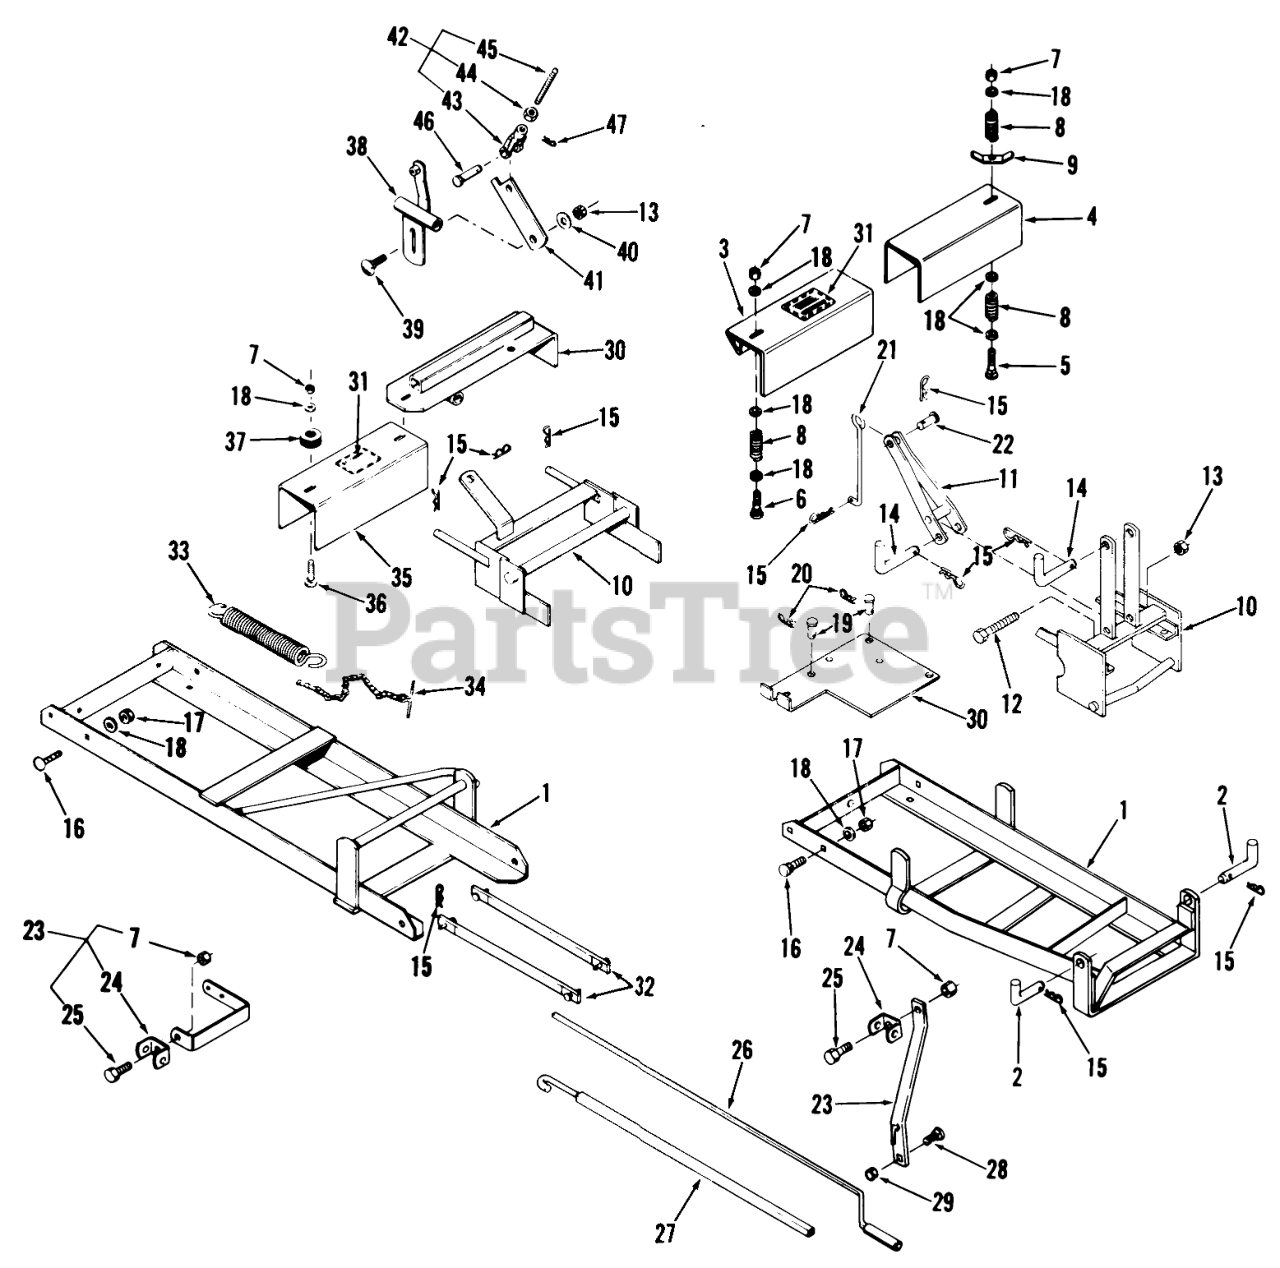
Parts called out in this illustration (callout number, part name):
1	Mounting Frame
3	PTO Cover (Top)
4	PTO Cover (Bottom)
5	Bolt
6	BOLT
7	Nut
8	SPRING
9	Wing Bracket
10	Gearbox MountingBracket
10	ASSEMBLY-BRACKET
11	Bell Crank Assembly
12	Bolt 1/2-13 x 3 1/2
13	Eslok Nut
15	Pin
16	Bolt
16	Bolt-Carriage
18	Washer
20	Pin
23	Crank Rod Support
23	Crank Rod Support Assembly
24	Crank Rod Guide
25	BOLT
26	Crank Rod
27	Crank Rod Extension
28	Bolt
29	Keps Nut 5/16-18
30	Gearbox Mounting Plate
30	Assembly-Gearbox Mtg.
31	Decal
32	Lift Bar
33	SPRING-EXTENSION
34	Chain and Toggle
35	PTO Cover
36	Carriage Bolt
37	Rubber Washer
38	Bracket-Gearbox Actuating
39	CARRIAGE BOLT -4
40	Washer
41	NDNK-OVER CENTER
42	Turnbuckle Assembly
43	Clevis
44	Nut
45	Stud
46	Clevis Pin
47	PIN-HAIR
